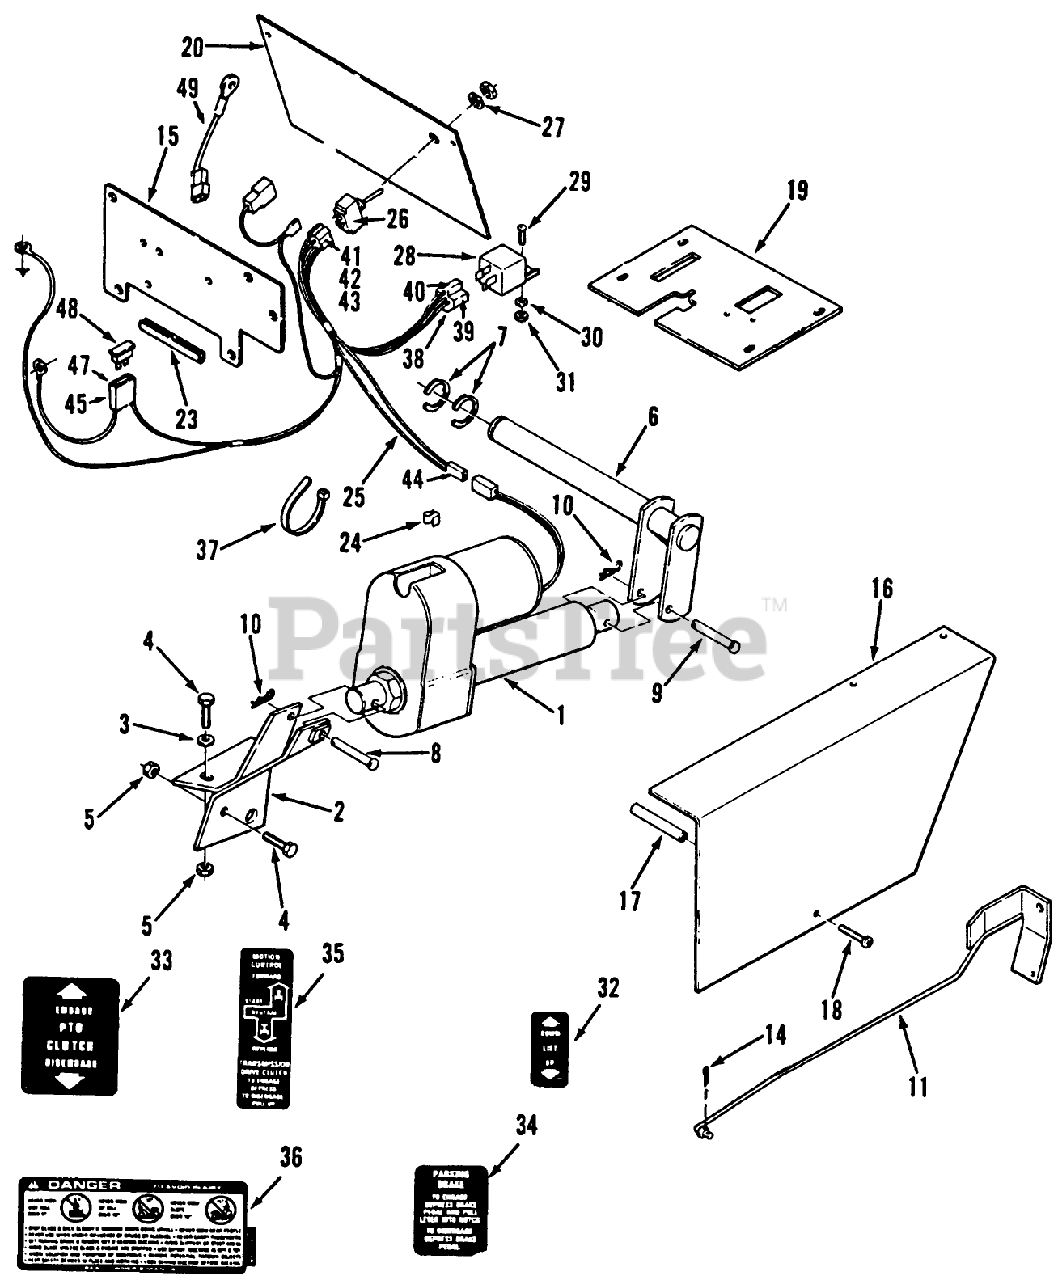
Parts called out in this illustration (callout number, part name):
1	Linear Actuator
2	ASSY LIFT BRACKET B
3	Washer
4	Bolt
5	NUT
6	ASSY LIFT ARM B
7	Retainer
8	Clevis Pin 1/2 x 2 3/4
9	CLEVIS PIN
10	Hairpin Cotter
11	Brake Rod
14	Pop Rivet
15	Front Hoodstand Plate
16	COVER-L.H. R
17	Spacer
18	Pan Head Screw 1/4-20 x 1 3/4
19	Shift Pattern Plate
20	Hoodstand Plate
23	EDGE TRIM 2" 102896
24	SPEED CLIP
25	Wiring Harness
26	SWITCH
27	Washer
28	RELAY
30	Washer
31	Nut
32	DECAL-LIFT
33	DECAL PTO CLUTCH
34	DECAL-PARKING, BRAKE
35	DECAL-MOTION CONTROL
36	DECAL-DANGER
37	PLASTIC TIE
38	Connector Body (Part of Item 10)
39	Female Terminal (Part of Item 10)
40	TERMINAL FEMALE
41	CONNECTOR 5 WAY
42	Terminal
43	TERMINAL-TAB RCPT
44	CONNECTOR BODY B
45	AUTO-FUSEBLOCK TERM
48	FUSE-BLADE, 25 AMP
49	Wire Adapter
